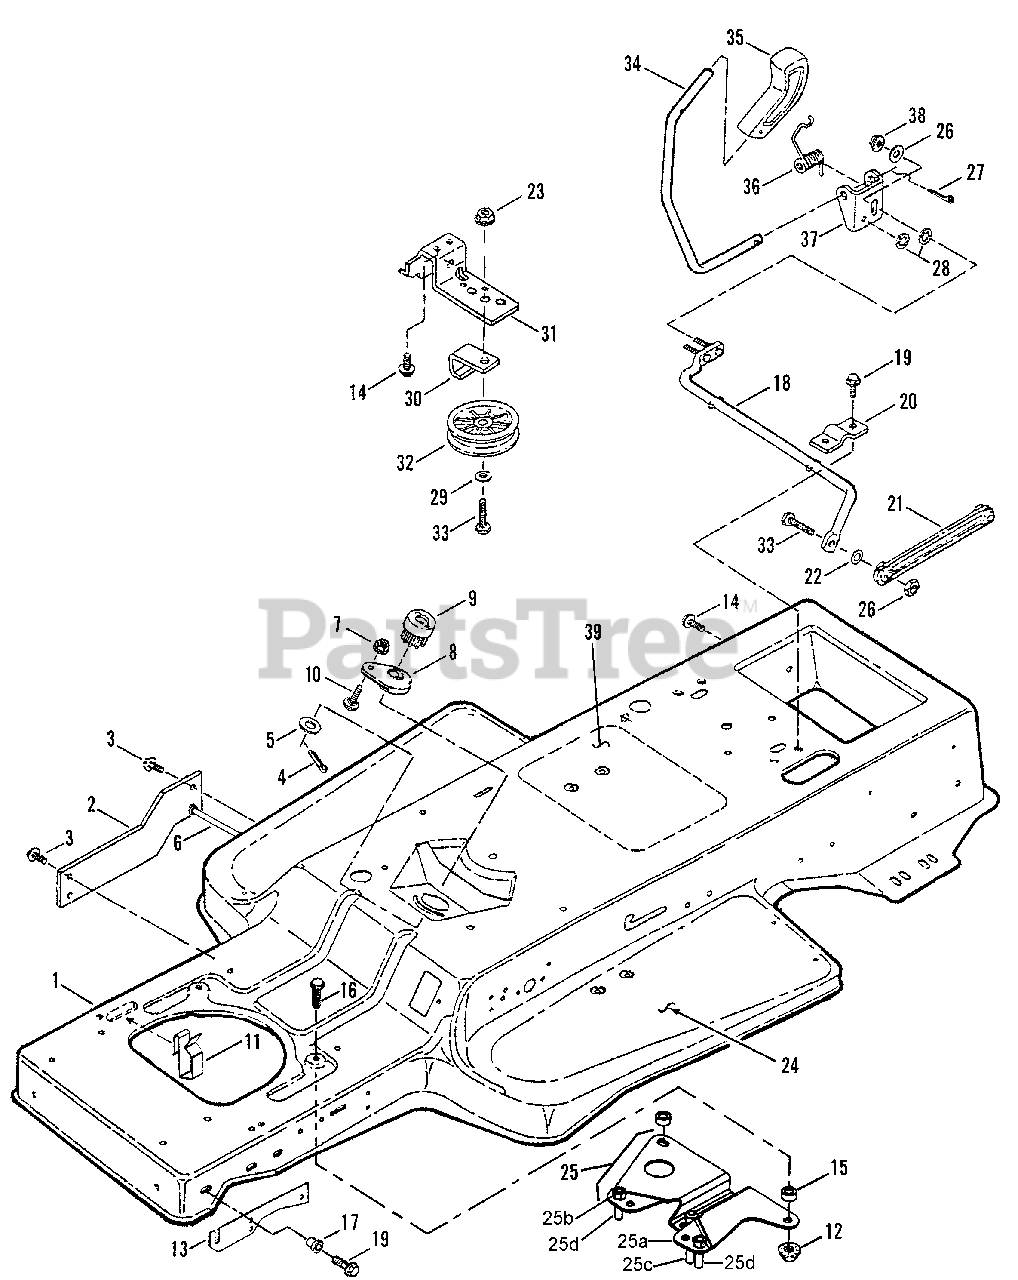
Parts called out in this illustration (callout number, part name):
1	FRAME, Tractor
2	BRACE, Frame
3	SCREW, 5/16-18 x 5/8" Truss Head (Torx)
4	PIN, 1/8 x 3/4" Cotter
5	WASHER, 1/2 Shim
6	GUIDE, Belt
7	NUT, 1/4-20 Hex Flange Lock, Grade 5
8	ASSEMBLY, Steering Adjuster
9	GEAR, Steering Pinion
10	BOLT, 1/4-20 x 5/8" Short Neck Carriage, Grade 5
11	CLIP, Wire
12	NUT, 5/16-18 Hex Flange Lock Grade 5
13	BRACKET, Hood Pivot
14	SCREW, 5/16-18 x 5/8" Self-Tap.
15	SPACER, 11/32 x 5/8 x 5/16
16	CAPSCREW, 5/16 - 18 x 1" Hex Head Grade 2
17	BUSHING, Flange
18	ASSEMBLY, Shift Lever (Lower)
19	SCREW, 5/16-18 x 1-1/4" Self-Tap.
20	CLIP 1/2" Dia.
21	LINK, Shift Lever (Upper)
22	SPACER
23	NUT, 3/8-16 Hex Center Lock, Grade 5 or B
24	PAD, Foot, Rubber Deluxe
25	ASSEMBLY, Anti-spin/Belt Guide
25A	BRACKET, Anti Spin Guide
25B	HCLN, 5/16-18 YZ
25C	PIN, .31" O.D. x 2"
25D	PIN, .31" O.D. x 1"
26	WASHER, 1/4 Flat
27	PIN, 5/32 x 1" Cotter
28	WASHER, 1/4 Internal Tooth Lock
29	WASHER, 3/8" Flat
30	GUIDE, Pulley Belt
31	SUPPORT, PTO Lever
32	PULLEY, Idler
33	SCREW, 3/8-16 x 1-1/2" Hex Hd. Cap, Grade 5
34	LEVER, Shift (Upper)
35	KNOB, Deck Lift Lever
36	SPRING, Shift Lever
37	BRACKET, Shift Lever (Upper)
38	NUT, 1/4-20 Hex Nylok
39	DECAL, Instruction
